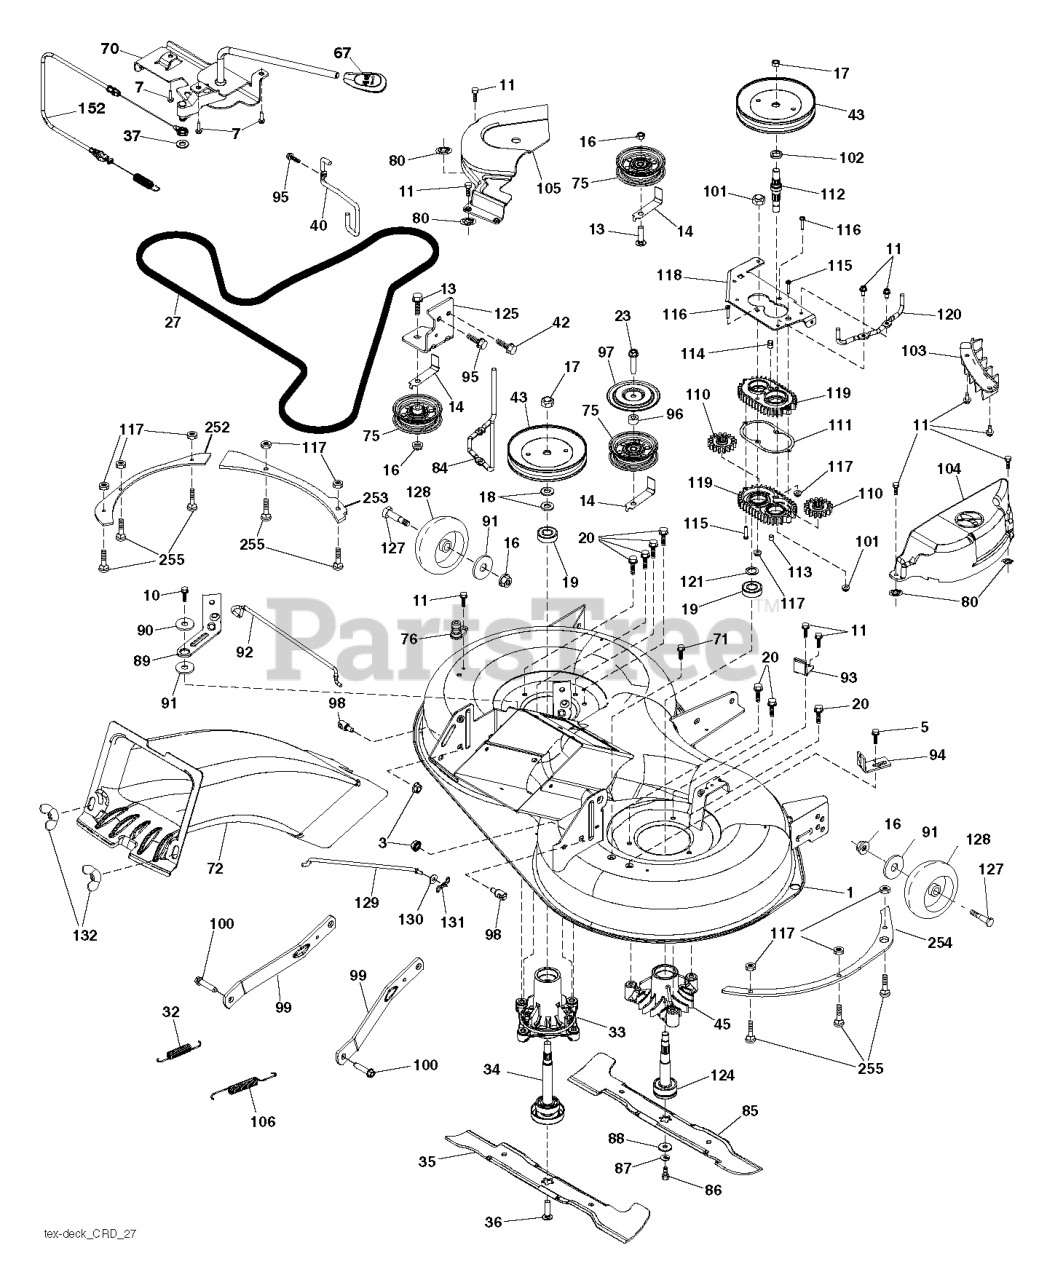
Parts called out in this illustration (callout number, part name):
1	DECK.WELDMENT.97.TEX.498
3	NUT LOCK HEX FLANGE 5/16-18
5	BOLT.5/16HEX.WHS.HD
7	SCREW.#10 X 0.750.BOS
10	SCREW 3/8-16X1
11	SCREW.1/4-20X5/8
13	BOLT.3/8-16X1.50
14	KEEPER, BELT IDLER
16	NUT LOCK FLG 3/8-16 UNC
17	NUT.FLANGE.LOCK.TOP
18	WASHER.SPACER.MANDREL
20	SCREW, WASHER HEAD
23	SCREW LT
27	BELT V-BELT DRIVE
32	SPRING RETURN
33	RP.HOUSING.MANDREL.4PT.
34	SHAFT.ASM.MDRL.N/GREASE.38
35	BLADE.3N1.LH.CRD.97
36	BOLT.WASHER.ASM.7/16-2
37	WASHER
40	KEEPER BELT ENGINE LH
42	SCREW
43	PULLEY.MANDREL.5.438.PD
45	HOUSING.MANDREL.44/46" VENT
67	HANDLE.CLUTCH.CABLE.LT
70	CLUTCH.ASM.MANUAL.LT.PRED
71	SCREW 3/8-16X1/2
72	CHUTE REAR CRD UPPER CHUTE TEX
75	FLAT IDLER PULLEY
76	PORT.WASHOUT
80	PALNUT 1/4
84	KEEPER.BELT.MANDREL.PULLEY
85	BLADE.3N1.RH.CRD.97
86	BOLT.3/8-24X1.25GR8. LHTHRD
87	LOCKWASHER
88	WASHER.BLADE
89	ARM.BRAKE.97.LH
90	SPACER.RETAINER
91	WASHER
92	ROD ROD BRAKE
93	ARM.BRAKE.97.RH
94	BRKT.CLUTCH.CABLE
95	SCREW, 3/8-16X3/4
96	SPACER
97	PROTECTOR
98	STUD.FASTNER.W/ANTI-ROTATE
99	ARM.SUSPENSION.MOWER.R
100	BOLT.SHOULDER
101	NUT.CROWNLOCK.9/16 -18.UNC
102	SPACER BEARING
103	GUARD GUARD FRONT VENT
104	97.CRD.RH.MANDREL.COVER
105	MANDREL MANDREL COVER LH
106	SPRING.BRAKE.RETURN.38"
110	CRD.SPUR.GEAR
111	GASKET GASKET GEARCASE
113	PLUG PLUG OIL
114	VALVE VALVE RELIEF
115	SCREW
116	BOLT.CARIGE.SS.1/4-20X1.75GR5
117	NUT T
118	ARM ARM CLUTCHING
119	GEARCASE GEARCASE SUBASM
120	BRACKET KEEPER BELT RH
121	WASHER WASHER
124	MANDREL SHAFT NON/GREASE
125	BRACKET BRACKET IDLER CHASSES
127	BOLT.SHOULDER.3/8-16X3-5/8.
128	RP WHEEL. GUAGE RALLY
129	ROD.ANTI.SWAY.48/54"K4
130	WASHER
131	PIN.COTTER.5/16.BOW TI
132	KNOB.HANDLE.3/8.TRI-POINT.BLAC
152	CABLE CABLE CLUTCH MANUAL W/S
252	PLATE 97 LEFT BOLT REINFORCING
253	PLATE 97 LH SIDE BOLT ON
254	PLATE 97 RH SIDE BOLT ON
255	RHSNB, 1/4-20 X 1, GR5
